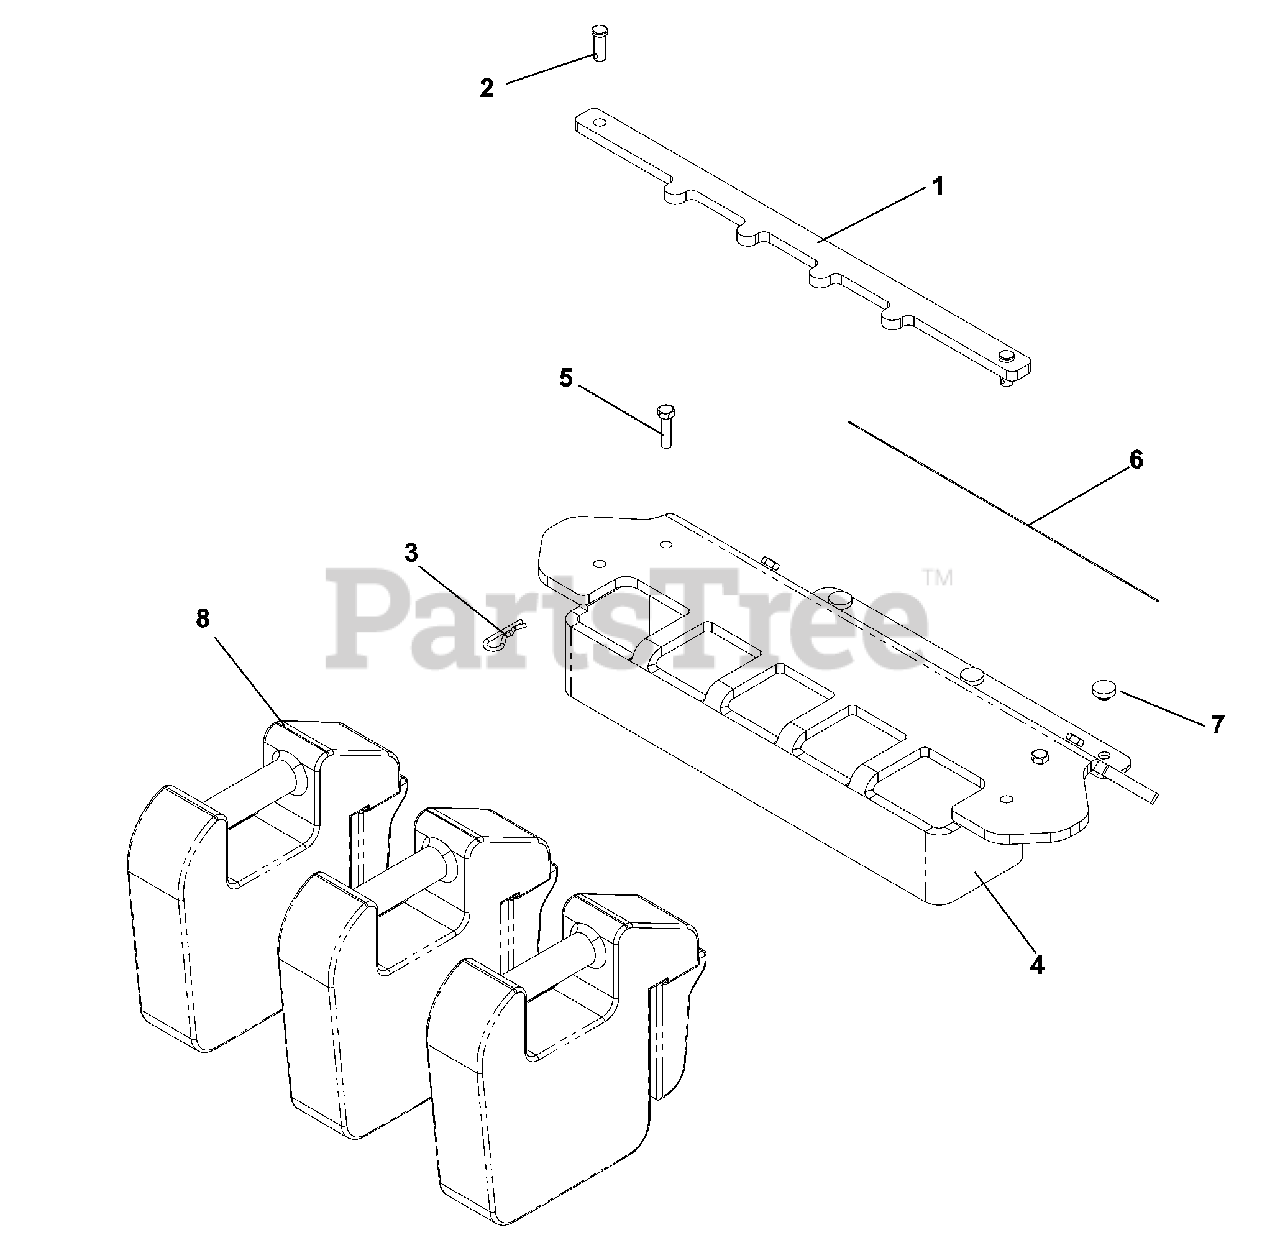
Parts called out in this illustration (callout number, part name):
1	HOLD DOWN, WEIGHT BAR
2	CLEVIS PIN
3	RETAINER SPRING
4	WEIGHT BAR
5	HCS 5/16C X 1 1/4
6	ANTI-SKID PAD
7	GROMMET, BUMPER
8	FRT WEIGHT CAST PZ DFS
